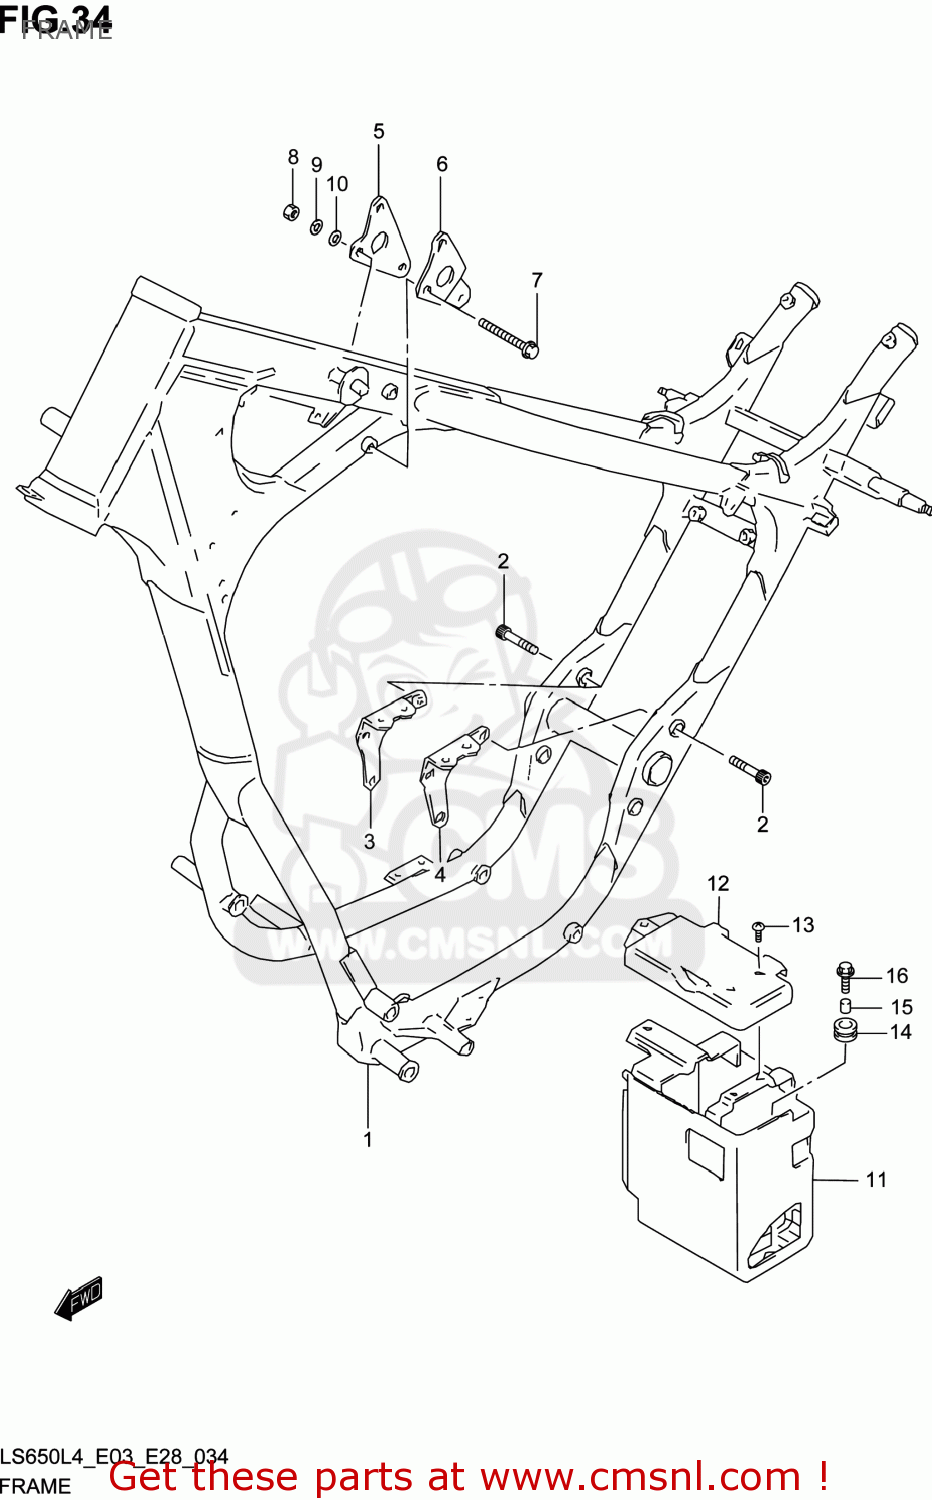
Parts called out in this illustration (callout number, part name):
1	FRAME(BLACK)
2	BOLT(8X40)
3	PLATE,ENGINE MOUNT NO.4,R
4	PLATE,ENGINE MOUNT NO.4,L
5	PLATE,ENGINE MOUNT NO.5,R
6	PLATE,ENGINE MOUNT NO.5,L
7	BOLT(8X72)
8	NUT
9	WASHER,LOCK
10	WASHER
11	HOLDER,BATTERY
12	COVER,BATTERY
13	SCREW
14	CUSHION
15	SPACER(6.5X9X7.2)
16	BOLT(6X20)
